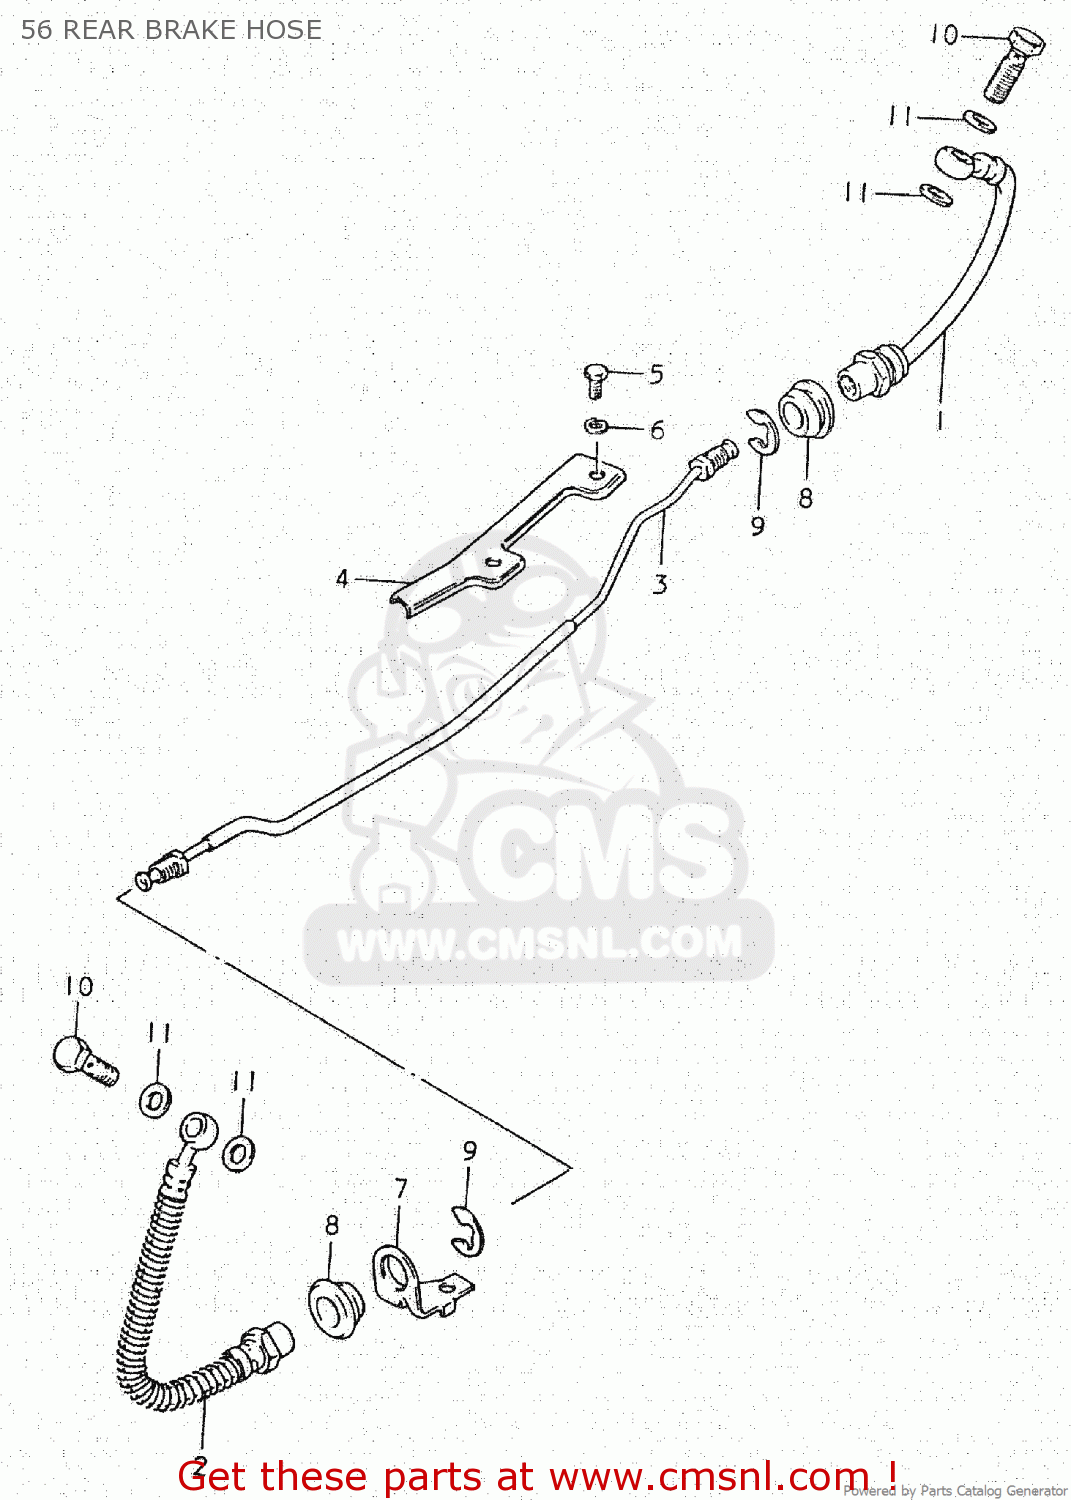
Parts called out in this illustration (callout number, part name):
1	HOSE,REAR BRAKE NO.1
2	HOSE,RR BRAKE NO.2
3	PIPE,REAR BRAKE
4	COVER,REAR BRAKE PIPE
5	BOLT(6X8)
6	LOCK WASHER
7	GUIDE,BRAKE HOSE
8	GROMMET,BRAKE HOSE GUIDE
9	E RING
10	BOLT UNION
11	WASHER
